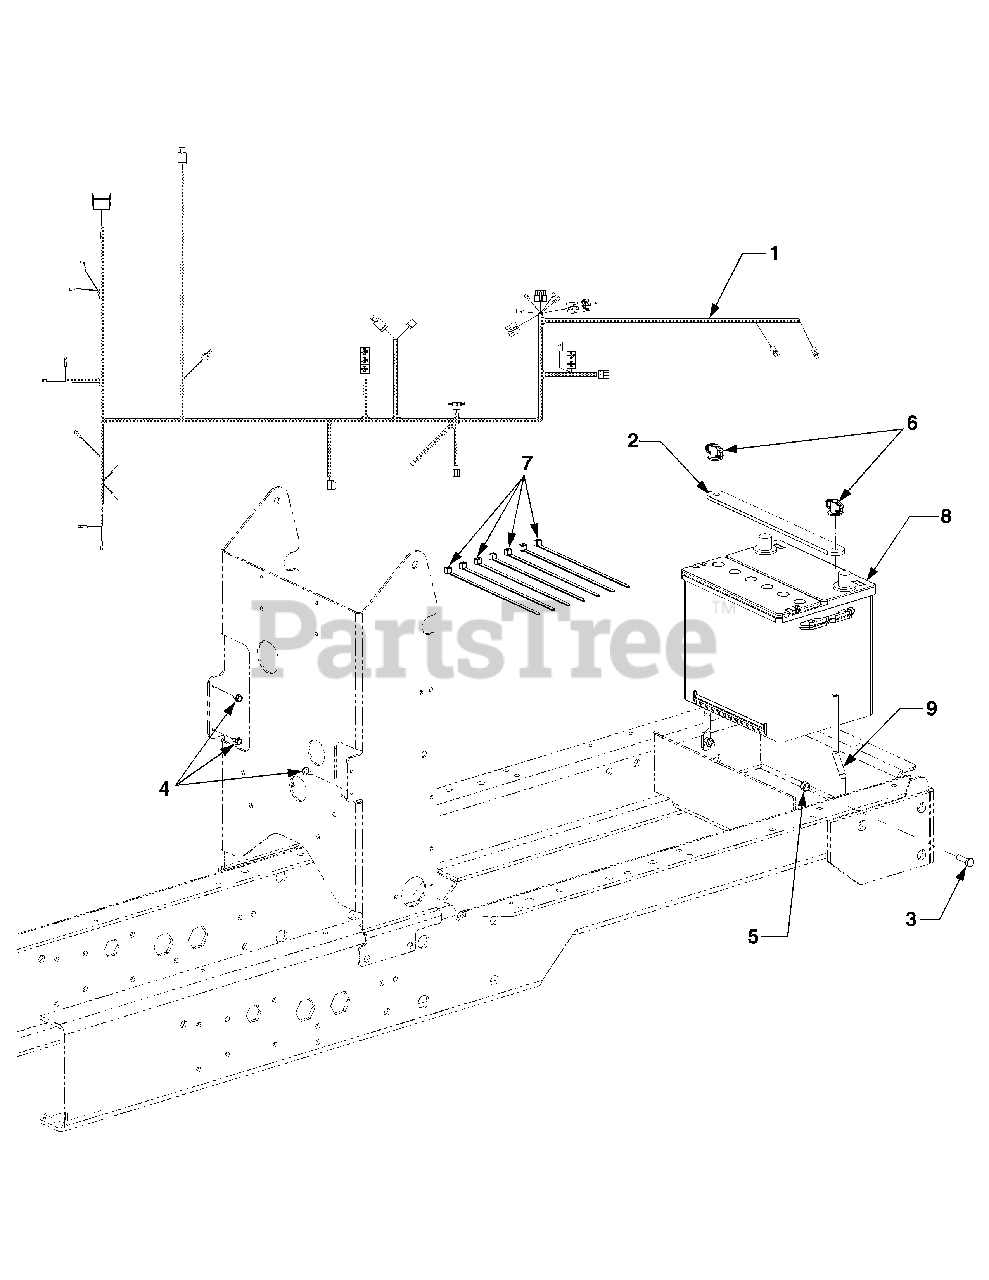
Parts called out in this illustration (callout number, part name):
1	Harness, Main Wire
2	Strap, Battery Holddown
3	Screw, Hex Cap, 1/4-10 x .875 GR5
4	Screw, Hex Wash Hd. Tapp #10-16 x .5
5	Nut, Hex Nylon Insert Lock, 1/4-20
6	Nut, Wing w/Bell Washer, 5/16-18
7	Tie, Cable
8	Battery, 500 cca Dry
9	Rod, Battery Holddown
